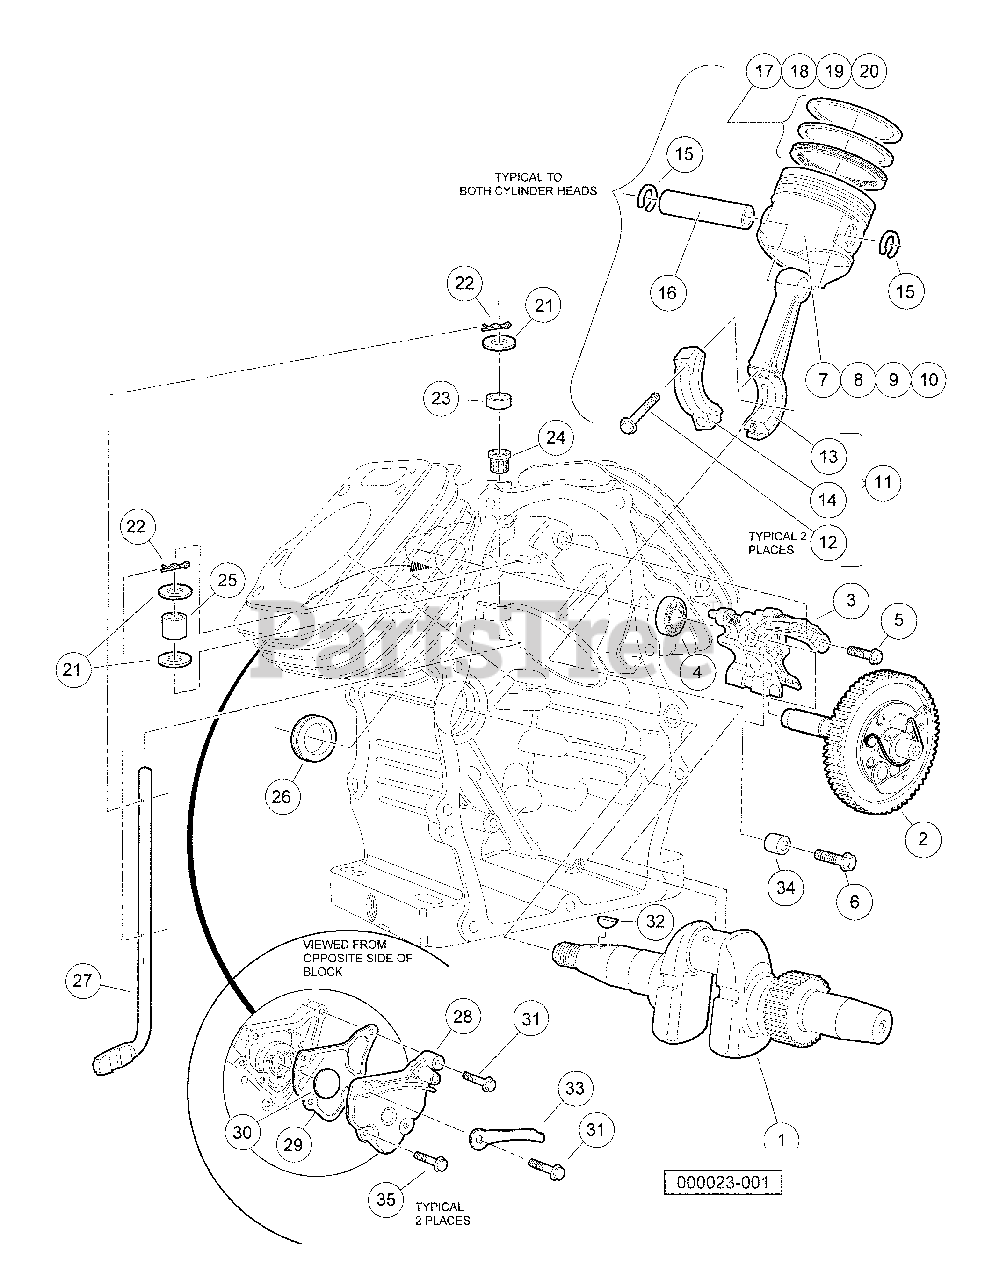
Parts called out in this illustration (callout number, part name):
1	Crankshaft
2	Camshaft Assembly
3	Lifter Assembly, Valve
4	Bearing, Radial Ball, 6003
5	Bolt, Flange Head, M5 X 1 X 16
6	Bolt, Flange Head, M6 X 1 X 25
7	Piston, Std
8	Piston, Over-Sized 0.25
9	Piston, Over-Sized 0.50
10	Piston, 0.75
11	Rod Assy., Connecting
12	Bolt, Connecting Rod, 6 X 37
13	Connecting Rod
14	Cap, Connecting Rod
15	Clip, Piston Pin, 18mm
16	Pin, Piston
17	Ring Set, Piston, Std
18	Ring Set, Piston, OS 0.25
19	Ring Set, Piston, OS 0.50
20	Ring Set, Piston, OS 0.75
21	Washer, Plain, M8
22	Pin, Lock, 8 Mm
23	Bearing, Needle, 8 X 12.7 X 11
24	Oil Seal, 8 X 14 X 5
25	Bearing, Needle, 8 X 12 X 10
26	Oil Seal, 38 X 58 X 9
27	Shaft, Governor Arm
28	Cover, Breather
29	Gasket, Breather Cover
30	Valve, Breather
31	Bolt, Flange Head, M6 X 1 X 32.
32	Key, Special Woodruff, 25 X 18
33	Clamp, Wire
34	Pin A, Dowel
35	Bolt, Flange Head, 6 X 16
